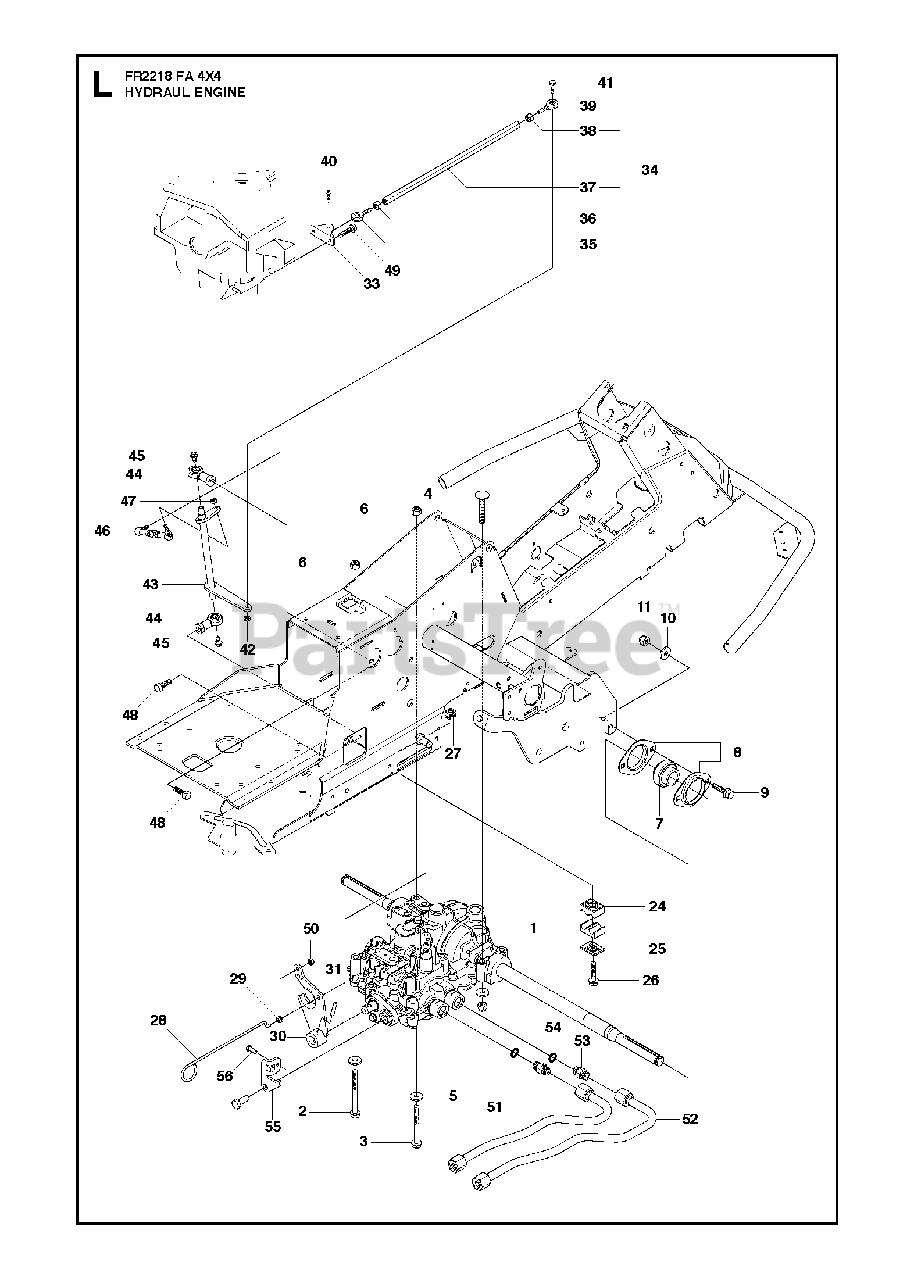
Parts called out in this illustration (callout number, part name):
1	TRANSMISSION
5	WASHER BRB 8.4X17
6	LOCKNUT M8
8	BEARING HOUSING
9	BOLT
10	WASHER BRB 8.4X17
11	LOCKNUT M8
24	PIPE CLAMP
25	COVER PLATE
26	SCREW EHHFM
29	FUEL TANK BUSHING
35	LINK
36	NUT
37	ROD
38	NUT
39	LINK
41	SCREW
42	LOCKNUT M6
45	SCREW EHHFM
46	ADJUSTING ROD
47	LOCKNUT M6
48	SCREW M10X25
50	LOCKNUT M6
51	HYDRAULIC PIPE
52	HYDRAULIC PIPE
53	PIPE FITTING
56	SCREW
